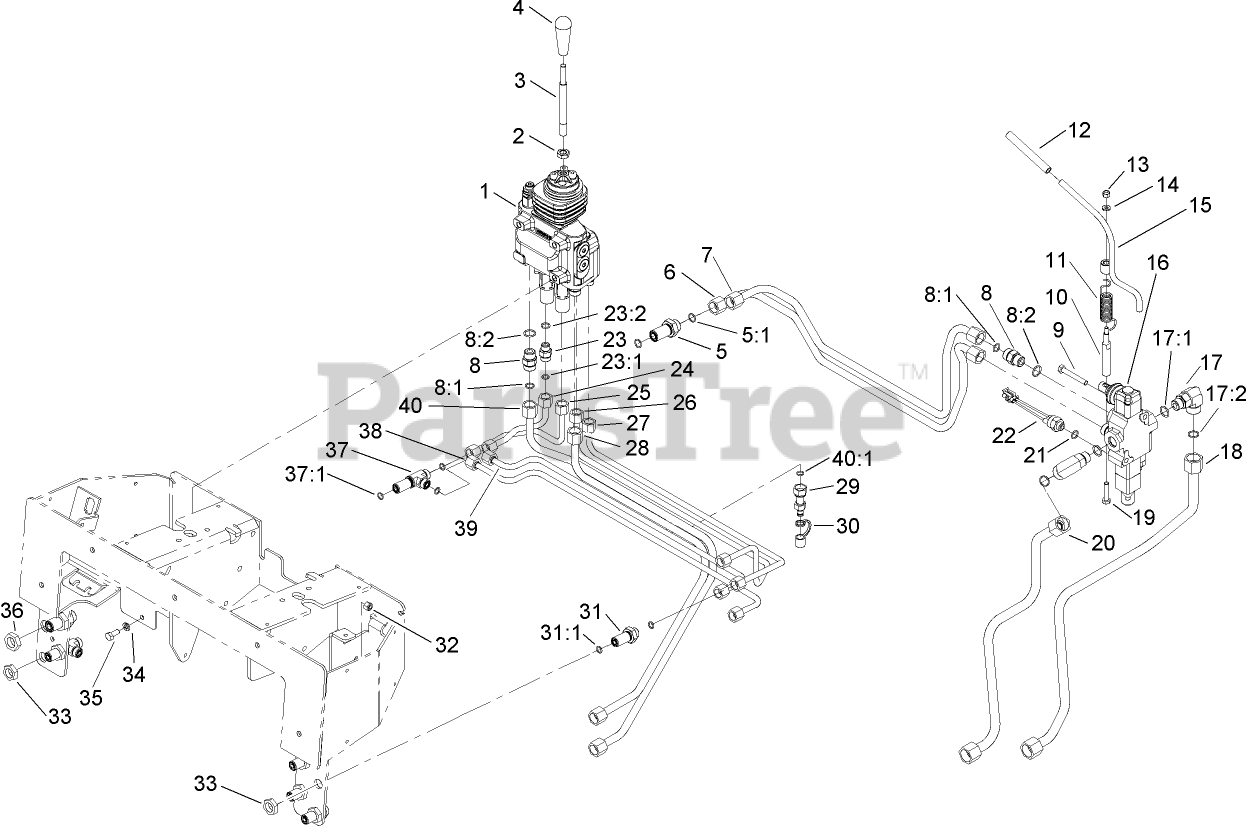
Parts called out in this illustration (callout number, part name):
1	2 SPOOL VALVE ASM
3	SHAFT-HANDLE, LIFT/TILT
4	KNOB-TAPERED
5	FITTING-BULKHEAD
5:1	O-RING
6	TUBE-HYD
7	TUBE-HYD
8	FITTING-STRAIGHT
8:1	O-RING
8:2	O-RING
9	SCREW-HH
10	SPACER-HIFLO
11	SPRING-TORSION
12	CAP-ROD, TILT
13	NUT-LOCK, NI
14	WASHER-FLAT
15	AUXILIARY LEVER ASM
16	1 SPOOL VALVE ASM
17	Fitting-Elbow, 90 DEG
17:1	O-RING
17:2	O-RING
18	TUBE-HYD
19	SCREW
20	TUBE-HYD
21	O-RING
22	SWITCH-BALL
23	FITTING-STRAIGHT
23:1	O-RING
23:2	O-RING
24	TUBE-HYD
25	TUBE-HYD
26	TUBE-HYD
27	TUBE-HYD
28	HYDRAULIC TUBE ASM
29	NIPPLE-TEST
30	CAP-DUST
31	FITTING-STRAIGHT, BULKHEAD
31:1	O-RING
32	NUT-LOCK, NI
33	NUT-LOCK
34	WASHER-LOCK
35	SCREW-HH
36	NUT-BULKHEAD
37	FITTING-TEE, BULKHEAD
37:1	O-RING
38	TUBE-HYD
39	TUBE-HYD
40	HYDRAULIC TUBE ASM
40:1	O-RING
